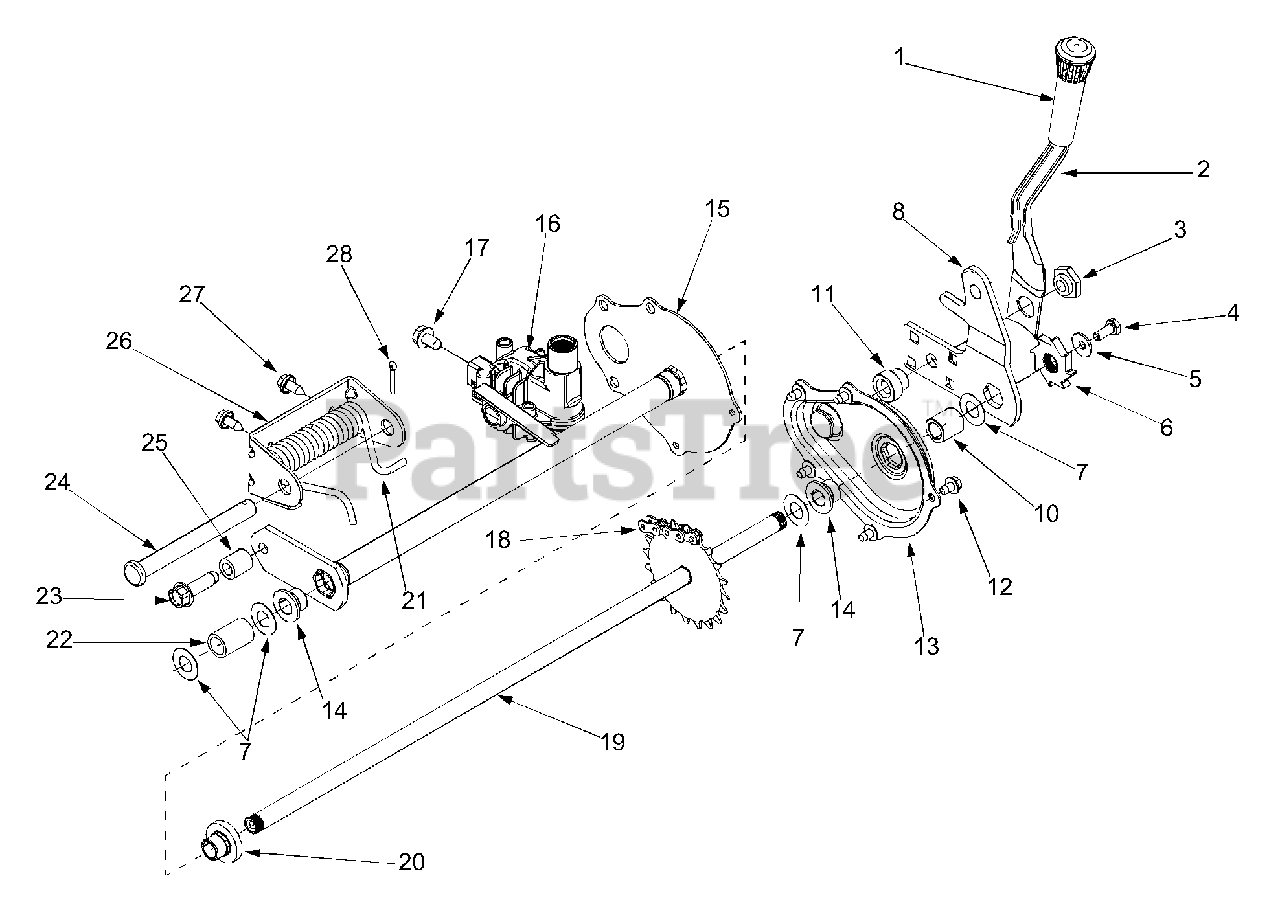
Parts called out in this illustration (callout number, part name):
2	Spring Lever
3	Shoulder Nut.825 x.165 Lg.
4	Cap Screw 1/4-20 x.620
5	Bell Washer.285 ID x.75 OD
6	Wheel Rachet
7	Flat Washer.508 ID x 1.0 OD
10	Sleeve Bearing.504 ID x.830 OD
11	Shoulder Spacer
12	Tap Screw 1/4-20 x.375
16	Transmission Assembly Complete
17	Hex Screw 5/16-18
18	Chain
19	Rear Axle Assembly
20	Flange Bearing.506 ID x.715 Lg
21	Torsion Spring
22	Spacer.550 ID x.750 OD
23	Screw 3/8-16 x.25
24	Clevis Pin.50 Dia x 4.82 Lg.
25	Spacer.385 ID x.624 OD
28	Cotter Pin
